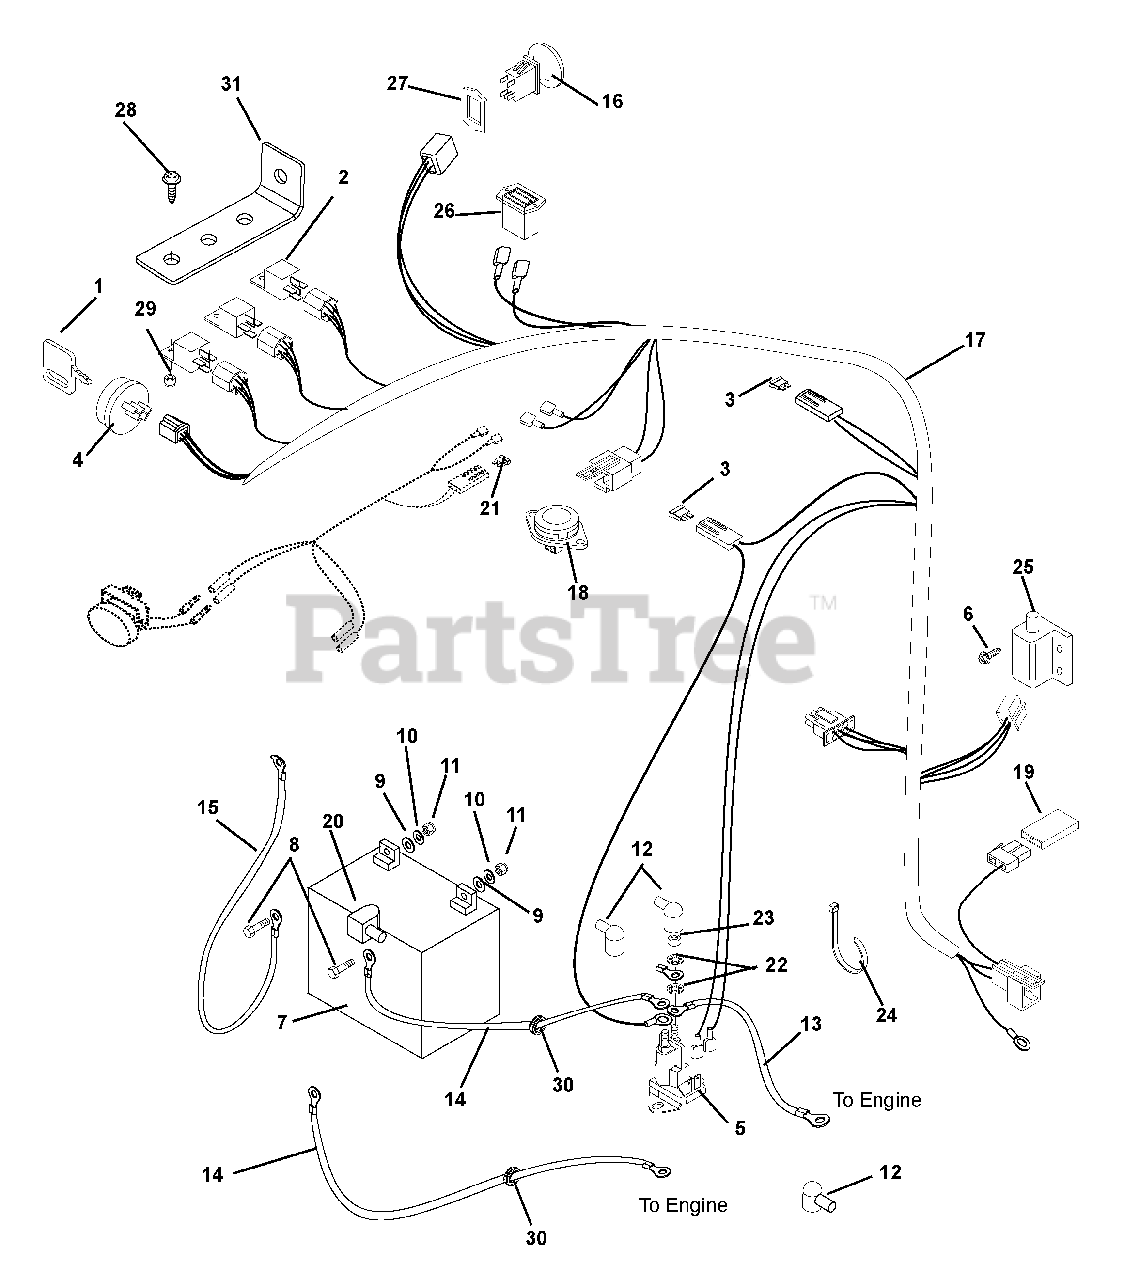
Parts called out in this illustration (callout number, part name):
1	KEY -W/CAP
2	RELAY,SEALED W/DIODE
3	FUSE-25 AMP ATC TYPE
4	KEY SWITCH
5	SOLENOID
6	@SCR-TAP 10-24X.50 HWH TR YWZC
7	BATTERY, 300 CCA 10U1L
8	@BLT-HEX .25-20X.75 GR5 YWZC
9	@WSHR-FL-STL.281X.62X.065 YWZC
10	@WSHR-LK .25X.062 REG YWZC
11	@NUT-HEX .25-20 YWZC
12	BOOT, EYELET TERMINAL
13	STARTER CABLE 6.75"
14	STARTER CABLE 16"
15	GROUND CABLE .31X22.00X.31
16	SWITCH, CLUTCH
17	WIRE HARNESS, ZT XL/ZOOM CE
17	WIRE HARNESS, ZOOM CE
18	SWITCH- SNAP MTG N.O.
19	DIODE, CONNECTOR SHELL
20	INSULATOR
21	FUSE 20AMP
22	WSHR-LOCK INT .31 YWZC
23	NUT-JAM .31-24 YWZC
24	CABLE TIE LG 5-1/2
25	SWITCH- DOUBLE POLE N.O./N.O.
25	SWITCH- SINGLE POLE N.O.
26	HOURMETER-QUARTZ 80VDCMAX
27	SHIM,PTO SW (DELTA #972301)
28	@SCR-MCH 10-24X.50 HWH YWZC
29	@NUT-LK-NYL 10-24 W/INSRT YWZC
30	GROMMET 1.0ID X 1.38 OD
31	BRACKET, RELAY
